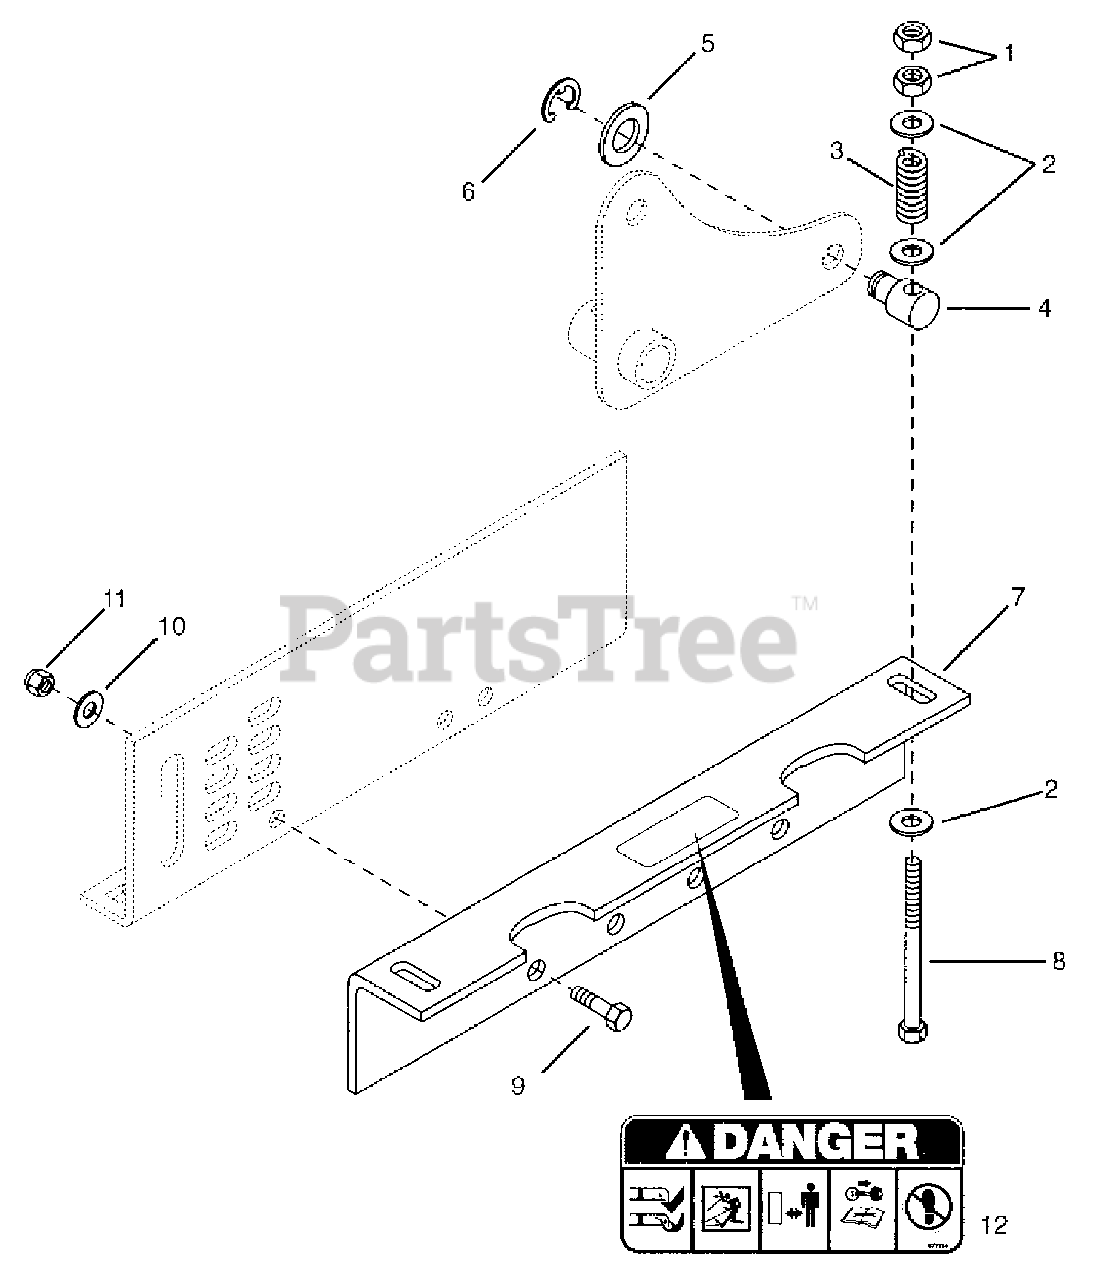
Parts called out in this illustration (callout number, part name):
1	Nut .50-13
2	Washer-Flat-Steel .52 x .827 x .062 (19527)
3	Spring-Compression .125 x .78 x 1.00
4	Pivot, Mower Lift
5	Washer-Flat-Steel .656 x 1.31 x .095
6	Ring-Retaining-External .750 x .050
7	Lift Bracket
8	Bolt-Hex .50-13 x 6.50 Grade 5
9	Bolt-Hex .38-16 x 1.25 Grade 5
10	Washer-Flat-Steel .406 x .812 x .065
11	Nut-Locking-Nylon .375-16
12	Decal Set-Deck
